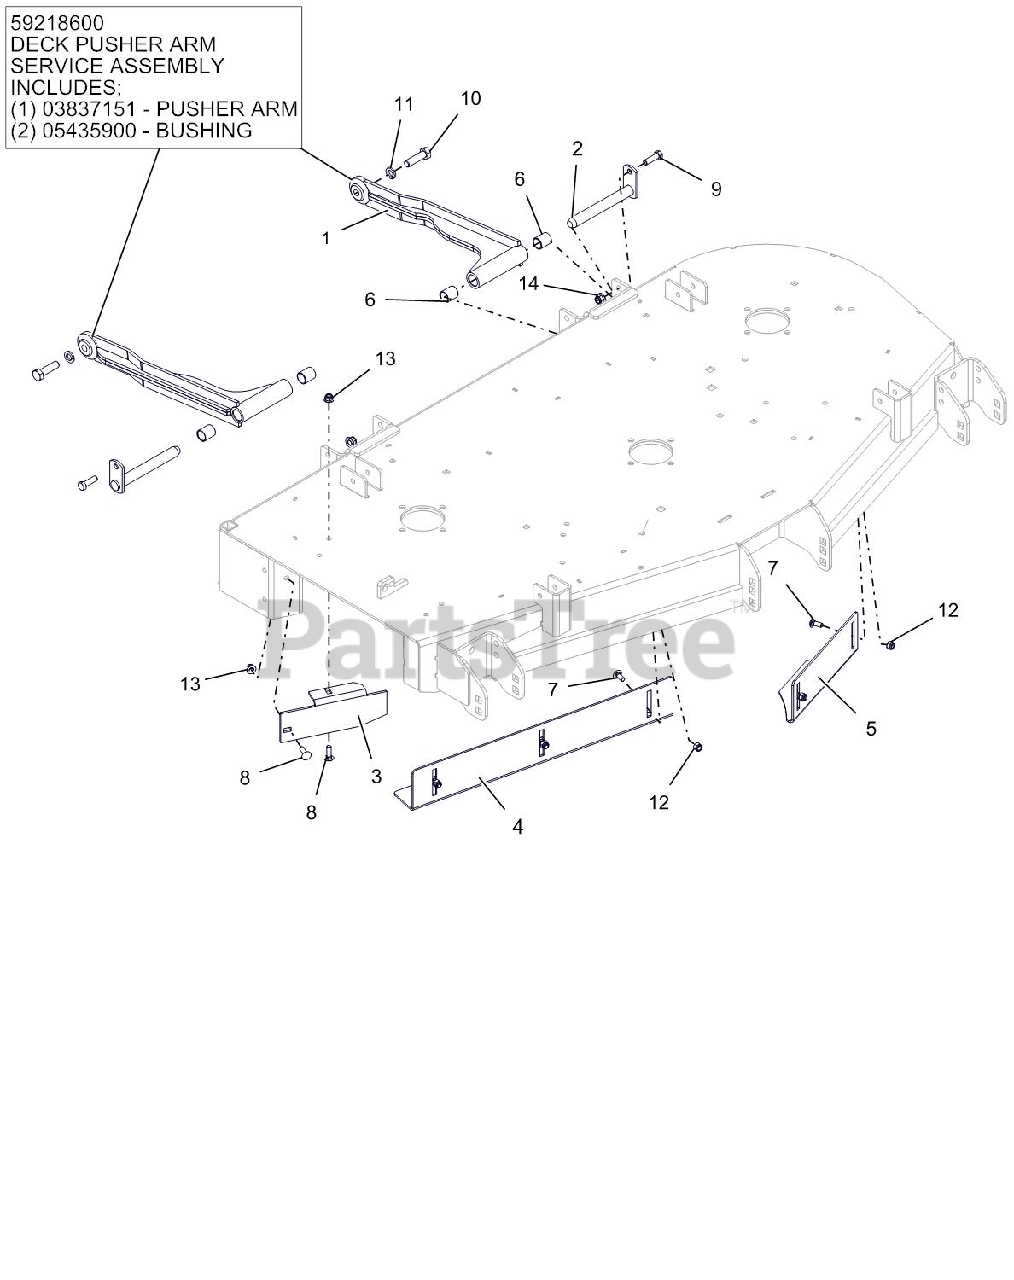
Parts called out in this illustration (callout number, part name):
1	BRG, .750 X .875 X 1.000
1	DECK STABILIZER ARM W/BUSHINGS
1	DECK STABILIZER ARM - BLACK
2	WELDMENT, MOWER MTG. PIN
3	52" DISCHARGE BAFFLE - RED
4	52" RH VACUUM BAFFLE - BLK
5	52" LH VACUUM BAFFLE - BLK
6	BRG, .750 X .875 X 1.000
7	@BLT-RDHDSQNK .31-18X.75 G5YZ
8	@BLT-RDHDSQNK .31-18X1.00 G5YZ
9	@BLT-HEX .38-16X1.25 GR5 YWZC
10	BLT-HEX .50-13X1.75 GR5EP80 YZ
11	@WSHR-LK .50X.125 REG YWZC
12	@NUT-LK-NYL .312-18 YWZC
13	@NUT-LK-NYL-FLG .31-18 YWZC
14	@NUT-LK-NYL-FLG .38-16 YWZC
